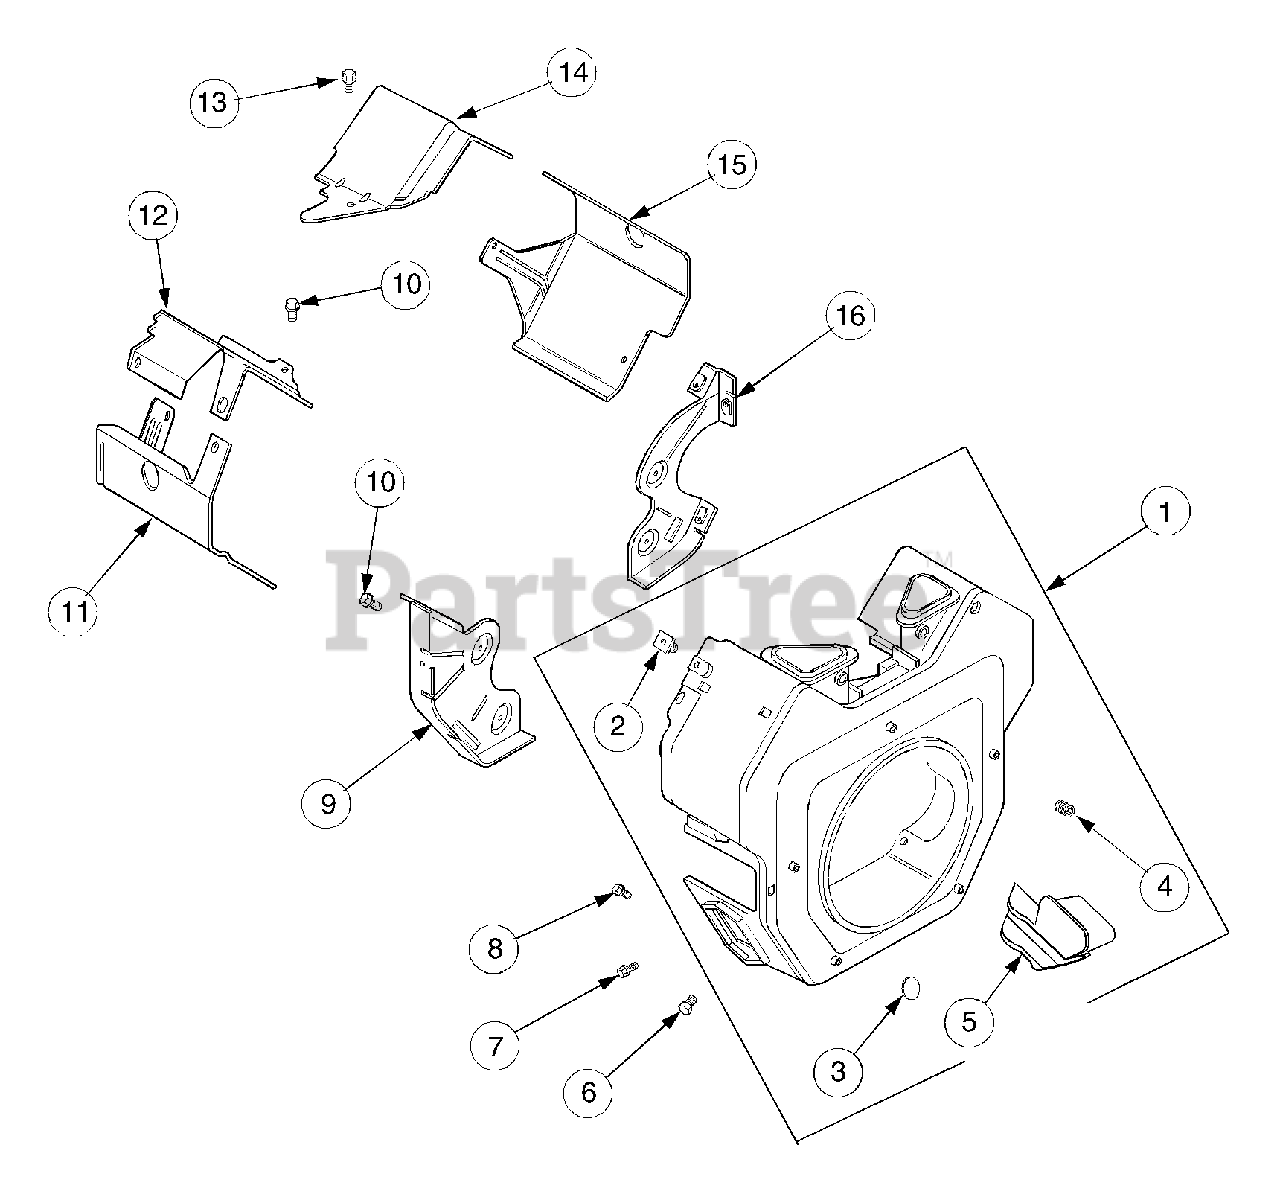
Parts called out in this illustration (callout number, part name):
1	Housing, Blower
2	Nut, Plastic
3	Plug, Button
4	Nut, Plastic
5	Cover, Blower Housing
6	Screw, Hex Flange, M5 x 0.8 x 16
7	Screw, Hex Flange, M5 x 0.8 x 16
8	Screw, Hex Flange, M5 x 0.8 x 20
9	Plate, Backing - #2 Side
10	Screw, Hex Flange, M6 x 1.0 x 16
11	Baffle, Cylinder Barrel - #2 Side
12	Baffle, Valley - #2 Side
13	Screw, Hex Flange, M5 x 0.8 x 10
14	Baffle, Valley - #1 Side
15	Baffle, Cylinder Barrel - #1 Side
16	Plate, Backing - #1 Side
